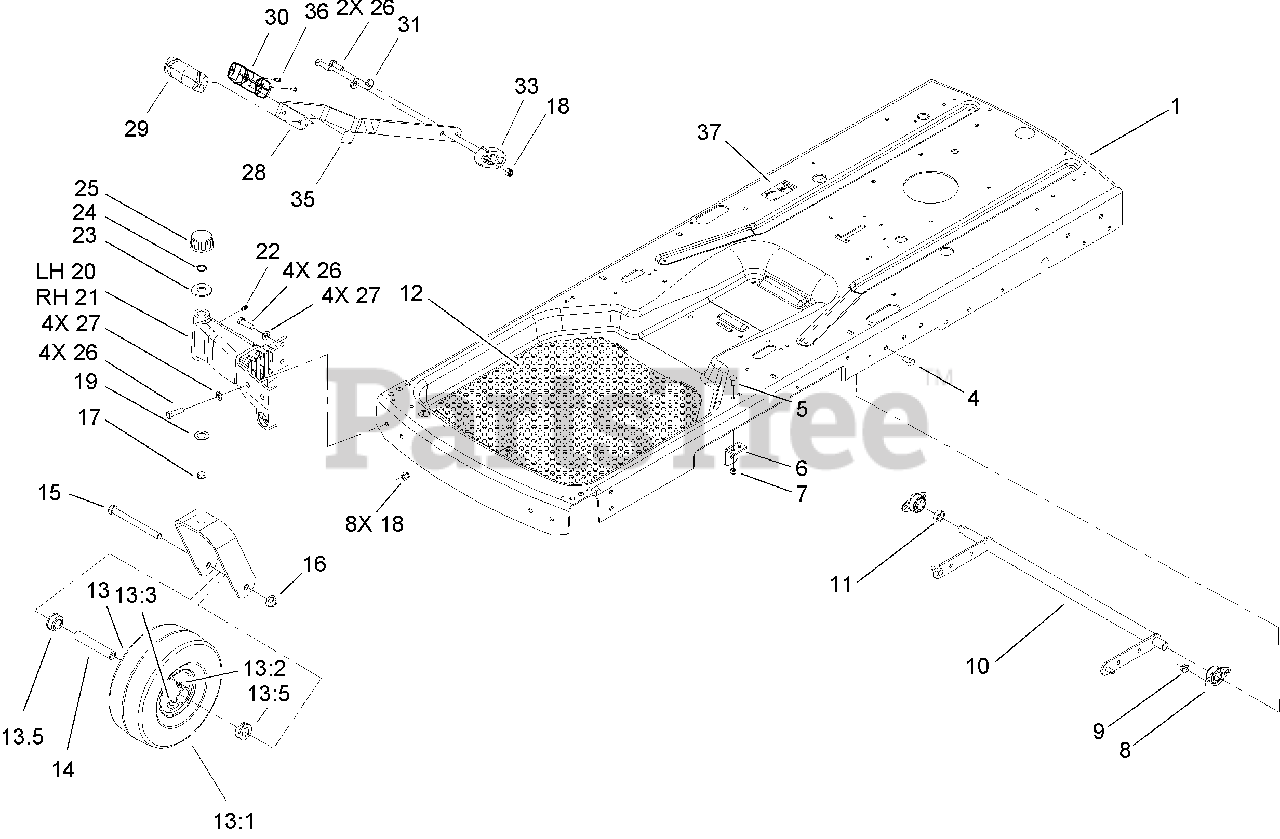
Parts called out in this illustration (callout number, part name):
4	SCREW-HH
5	SCREW-CARR
6	BRACKET-LIFT
7	NUT-LOCK, NI
8	BEARING-FLANGE, SIDE
9	NUT-HHF, WHIZ
10	LIFT ARM ASM
12	FOOTMAT-FRAME
13	CASTOR WHEEL ASM
13:2	FITTING-GREASE
13:3	STEM-VALVE
13:5	BUSHING-FLANGE
14	SPANNER-WHEEL
15	SCREW-HH
17	CASTOR FORK ASM
18	NUT-LOCK, NI
19	WASHER-THRUST
22	FITTING-GREASE
24	RING-RETAINING, EXT
26	SCREW-HH
27	WASHER-FLAT
29	HANDLE-TOP
30	HANDLE-BOTTOM
31	WASHER-BELLEVILLE
33	BLOCK-LIFT
37	DECAL-TRANSPORT, CE
